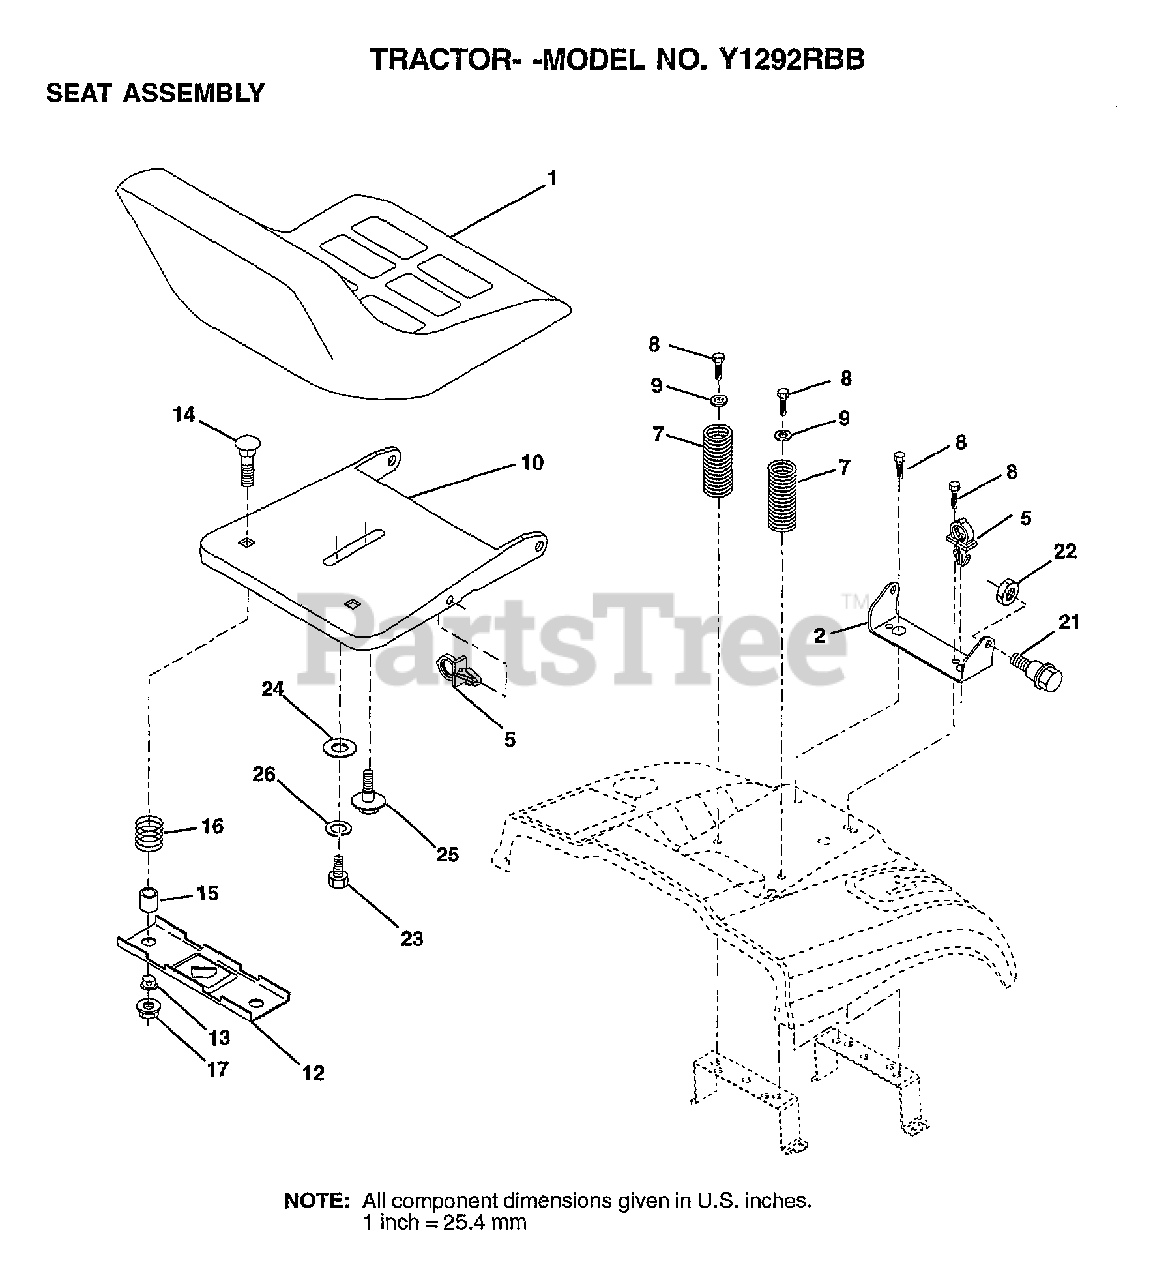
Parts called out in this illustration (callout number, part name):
2	BRACKET PVT SEAT
5	CLIP.PUSH-IN.HING
7	SPRING COMPRESSIO
8	SCREW
9	WASHER
10	PAN-SEAT
12	BRKT SWITCH
13	BUSHING
14	BOLT-RD HD SQ NK
15	SPLIT SPACER
16	SPRING
21	BOLT
22	NUT
23	BOLT
24	WASHER
25	"BOLT,SHOULDER"
26	LOCKWASHER
